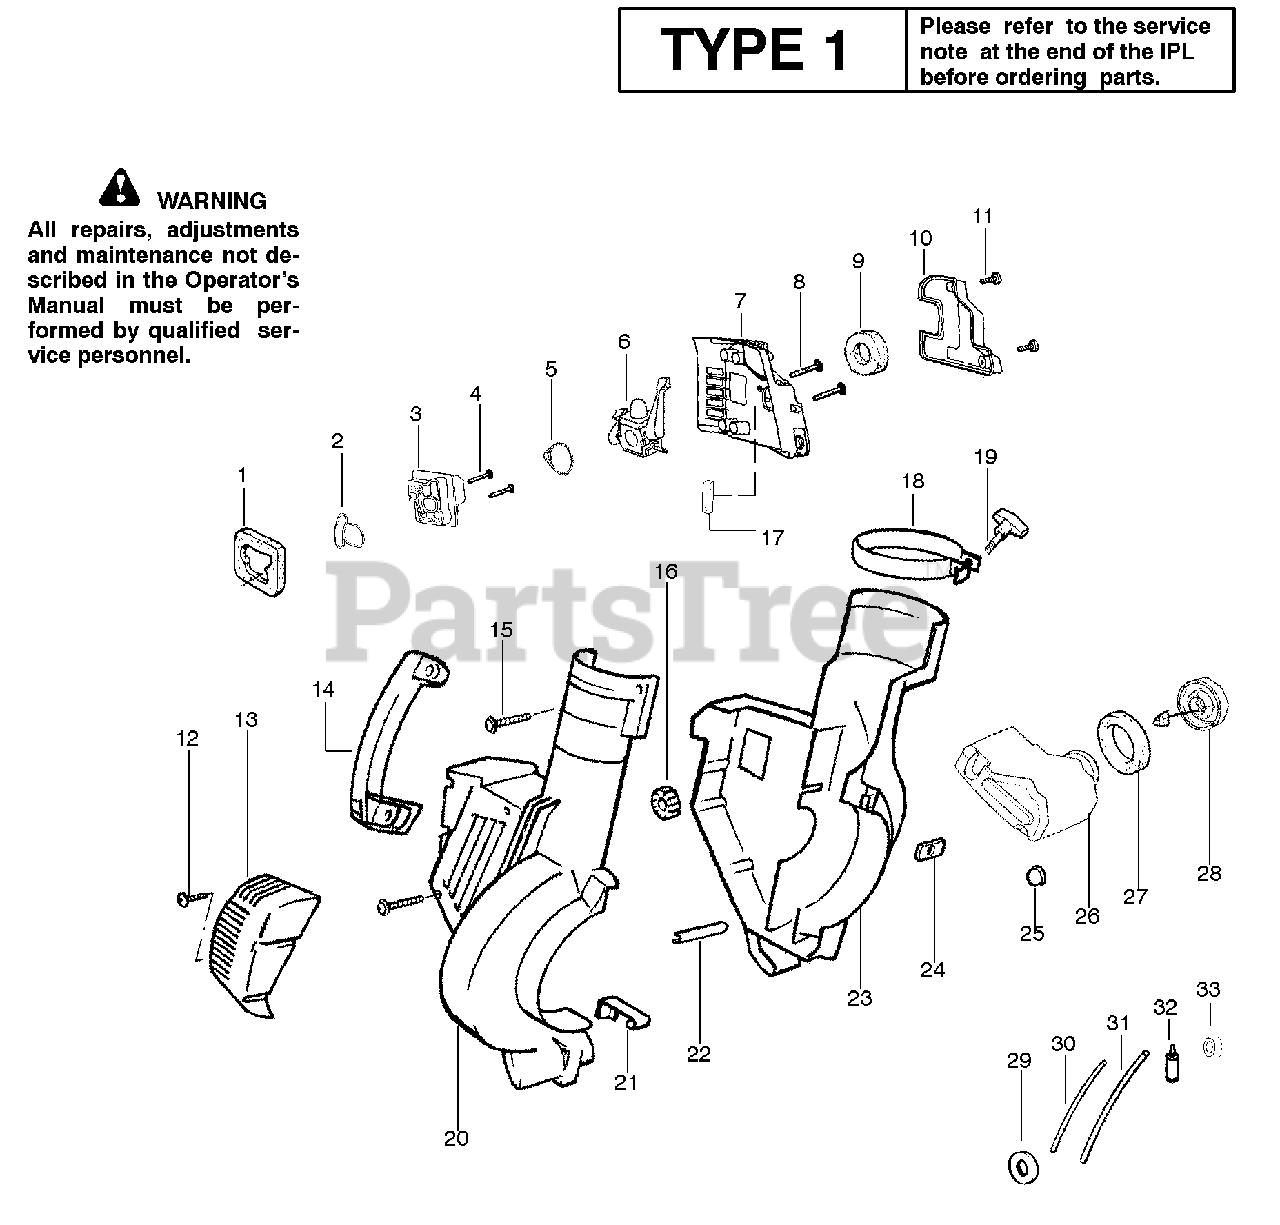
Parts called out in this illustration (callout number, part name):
1	Air Dam (kit)
2	Gasket-Adapter (kit)
3	Carburetor Adaptor
5	Gasket-Carburetor (kit)
6	Kit-Carb Ass'y. (C1Q-W11)
8	Screw-Carb.
9	Filter-Air
10	Cover-Air Filter
11	Screw-Air Box Cover
13	Assy-Muffler Cover
16	Isolator
17	Foam 25.4mm (kit)
18	Clamp-Blower Tube
19	Knob-Tube Clamp
20	Housing-Right
21	Spring-Cover Latch
22	Guide-Starter Rope
23	Housing-Left
25	Isolator-Crankcase
26	Assy-Fuel Tank
27	Gasket-Fuel Tank
28	Fuel Cap w/Retainer
29	Grommet-Shroud
30	Kit-Line Carb/Purge
31	Kit-Line Tank/Purge
32	Assy-Fuel Pick-up
33	Grommet-Fuel line (kit)
